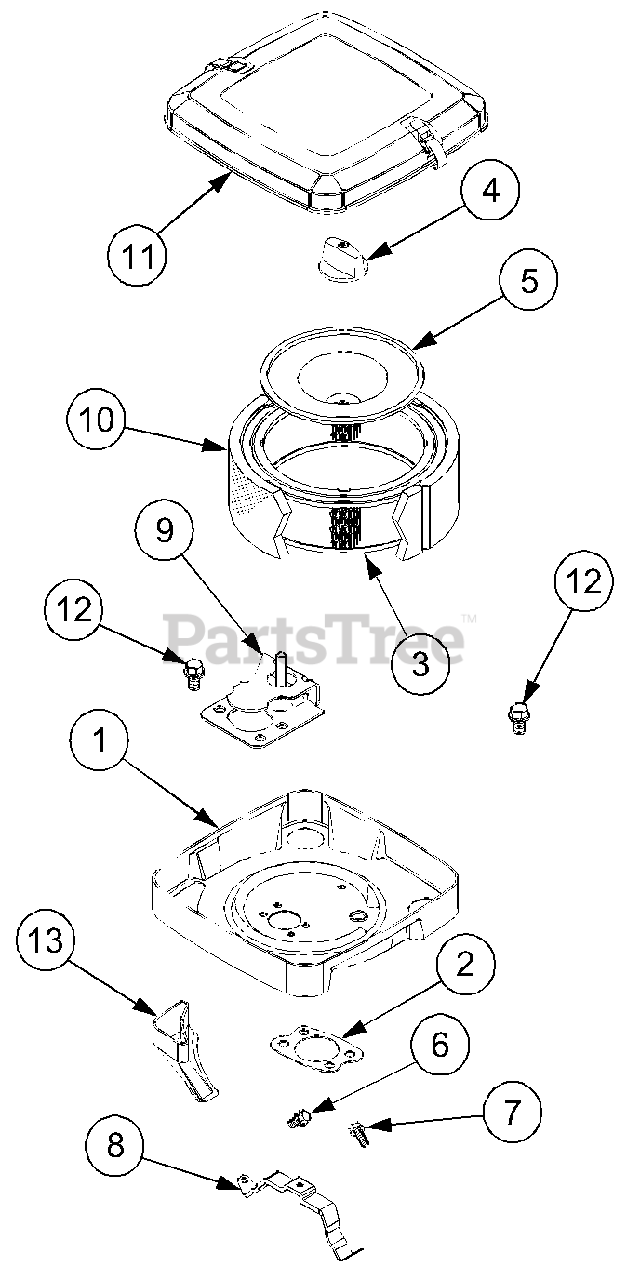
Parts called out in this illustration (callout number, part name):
1	Base, Air Cleaner
2	Gasket, Air Cleaner
3	Filter, Air Cleaner Cartridge
4	Knob, Air Cleaner
5	Retainer, Air Filter
6	Screw, Cleaner Mounting Strap
7	Screw, Cleaner Mounting Strap
8	Strap, Air Cleaner Mounting
9	Shield, Carburetor
10	Pre Cleaner, Filter
11	Cover, Air Cleaner
12	Screw, Air Cleaner Base
